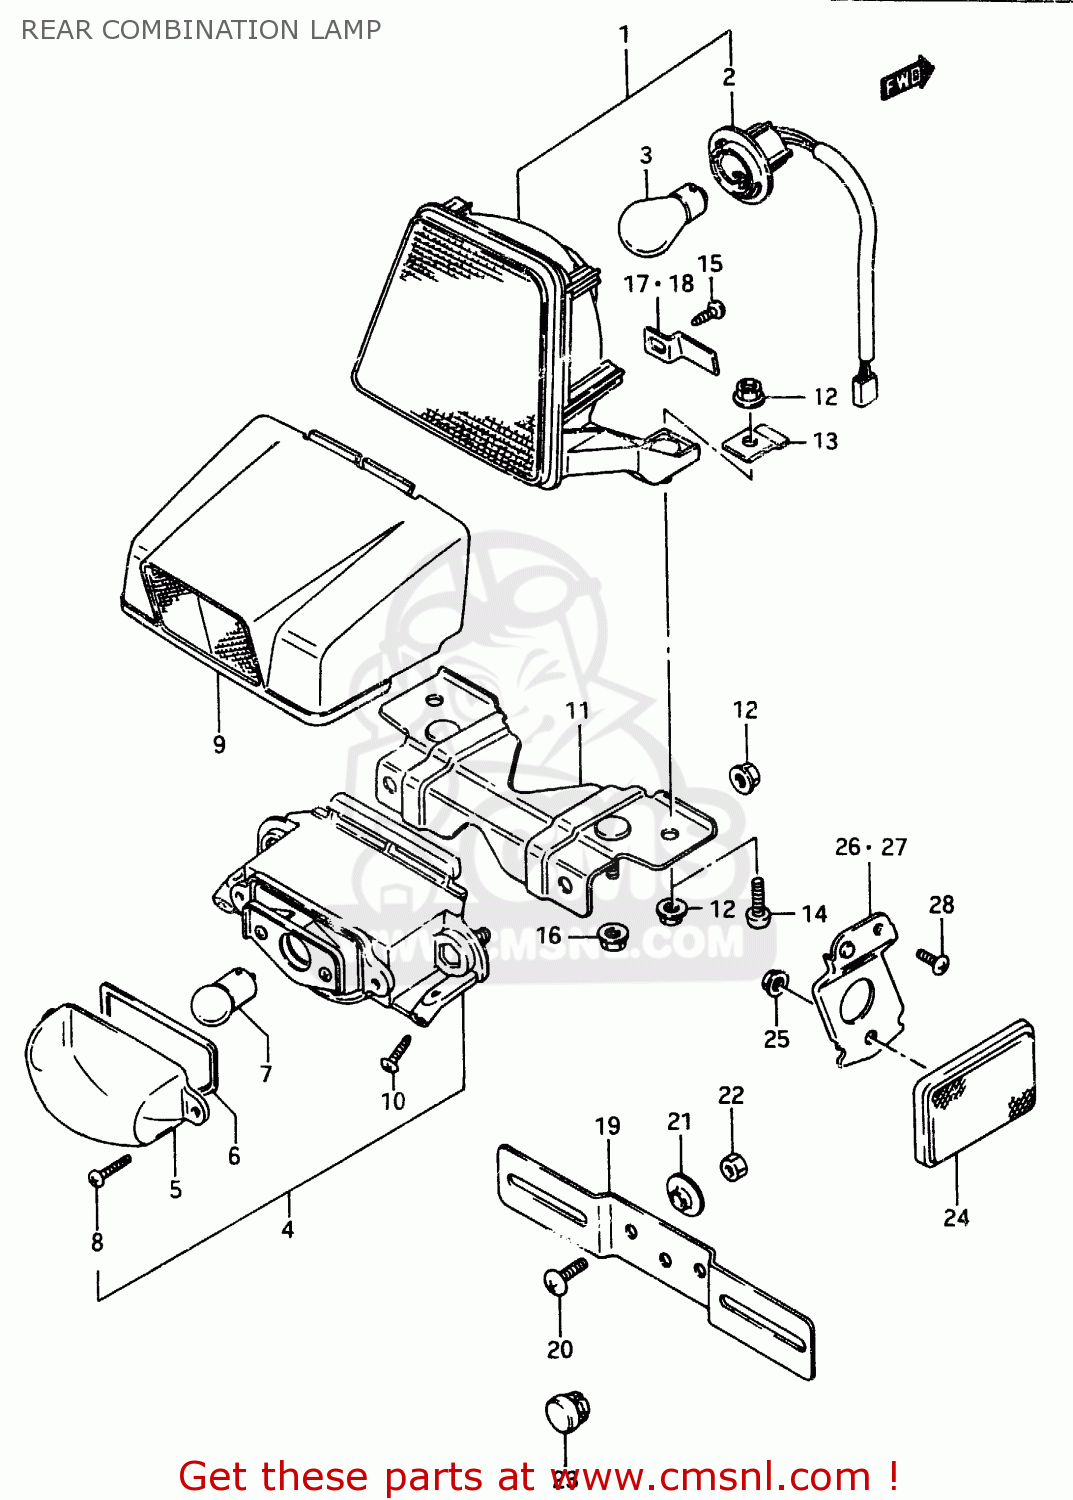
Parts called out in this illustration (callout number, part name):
1	LAMP ASSY, REAR COMBINATION
2	SOCKET
3	BULB(12V21/5W)
4	LAMP ASSY, LICENSE PLATE
5	LENS,LICENSE LAMP
6	GASKET,LICESE LAMP (NAS)
7	BULB
8	SCREW
9	COVER,LICENSE LAMP
10	SCREW
11	BRACKET, TAIL LAMP
12	NUT
13	PLATE,TAIL LAMP
14	SCREW
15	SCREW
16	NUT
17	PLATE, RH
18	PLATE, LH
19	PLATE,RR LICENSE
20	SCREW
21	WASHER,LOCK
22	NUT
23	CUSHION
24	REFLEX REFLECTOR, REAR SIDE
25	NUT
26	BRACKET, RH
27	BRACKET, LH
28	SCREW
